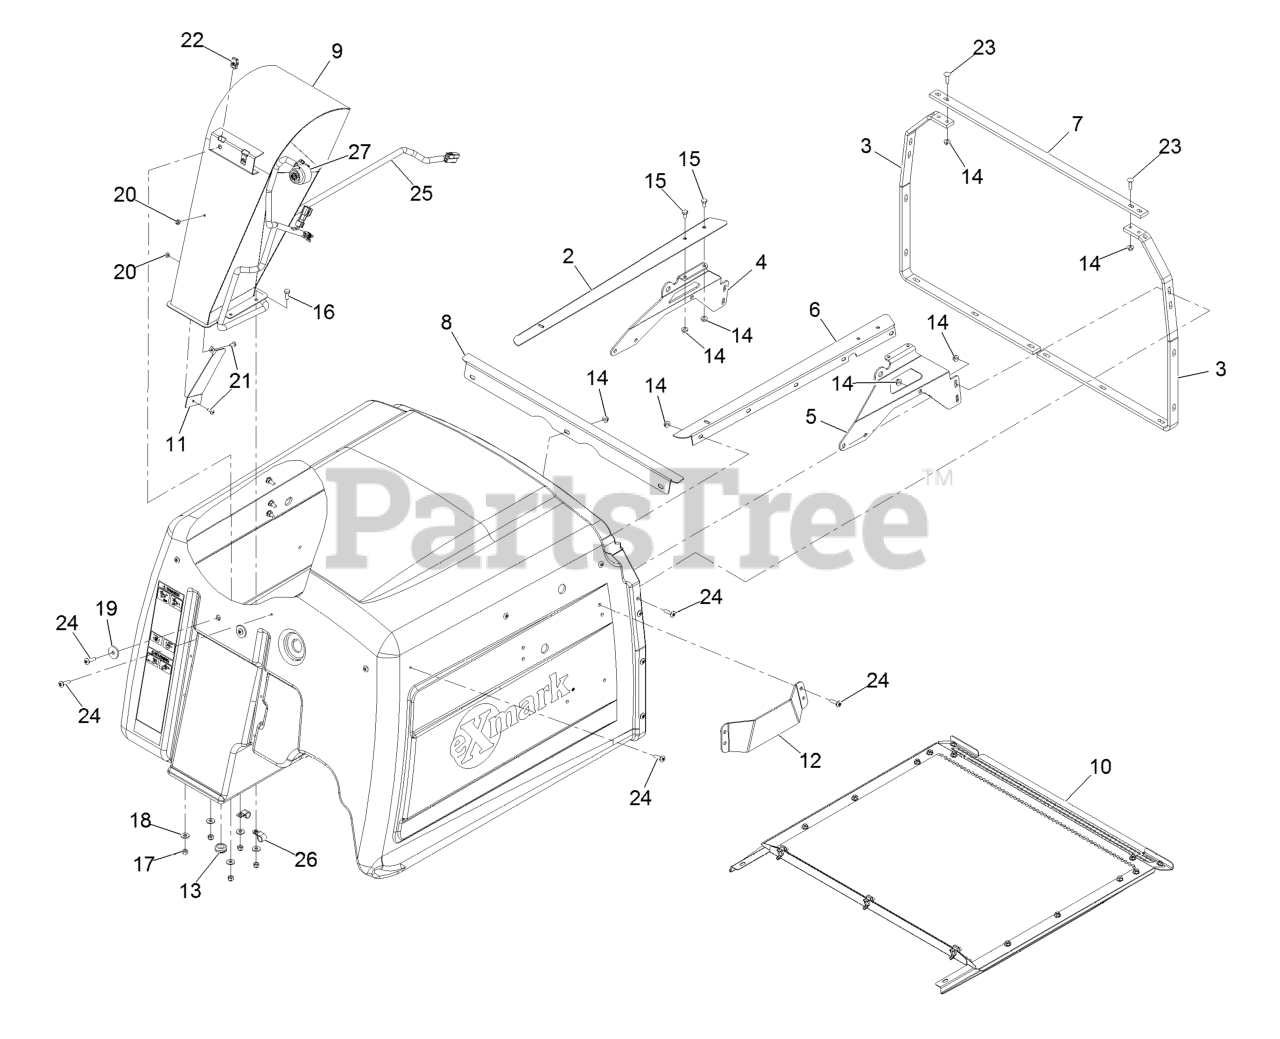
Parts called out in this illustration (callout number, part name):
2	ANGLE-SCREEN TRACK, RH
3	REINFORCEMENT-HOPPER
4	BRACE-DOOR PIVOT, RH
5	BRACE-DOOR PIVOT, LH
6	ANGLE-SCREEN TRACK, LH
7	BRACKET-FRAME CONNECT
8	CHANNEL-SCREEN, FRONT
10	HOPPER SCREEN ASM
11	DEFLECTOR-DISCHARGE CHUTE
12	PLATE-GUARD
13	GROMMET
15	SCREW-HH
16	SCREW-HH
17	NUT-LOCK, NI
18	WASHER-FLAT
20	NUT-LOCK, NI
21	SCREW-PTH
22	Nut-Retainer-Panel 1/4-20
23	SCREW-CARR
24	SCREW-TTH
25	HARNESS-WIRE, HOPPER
26	CLIP-LOOM
27	ALARM-TONE, DUAL
